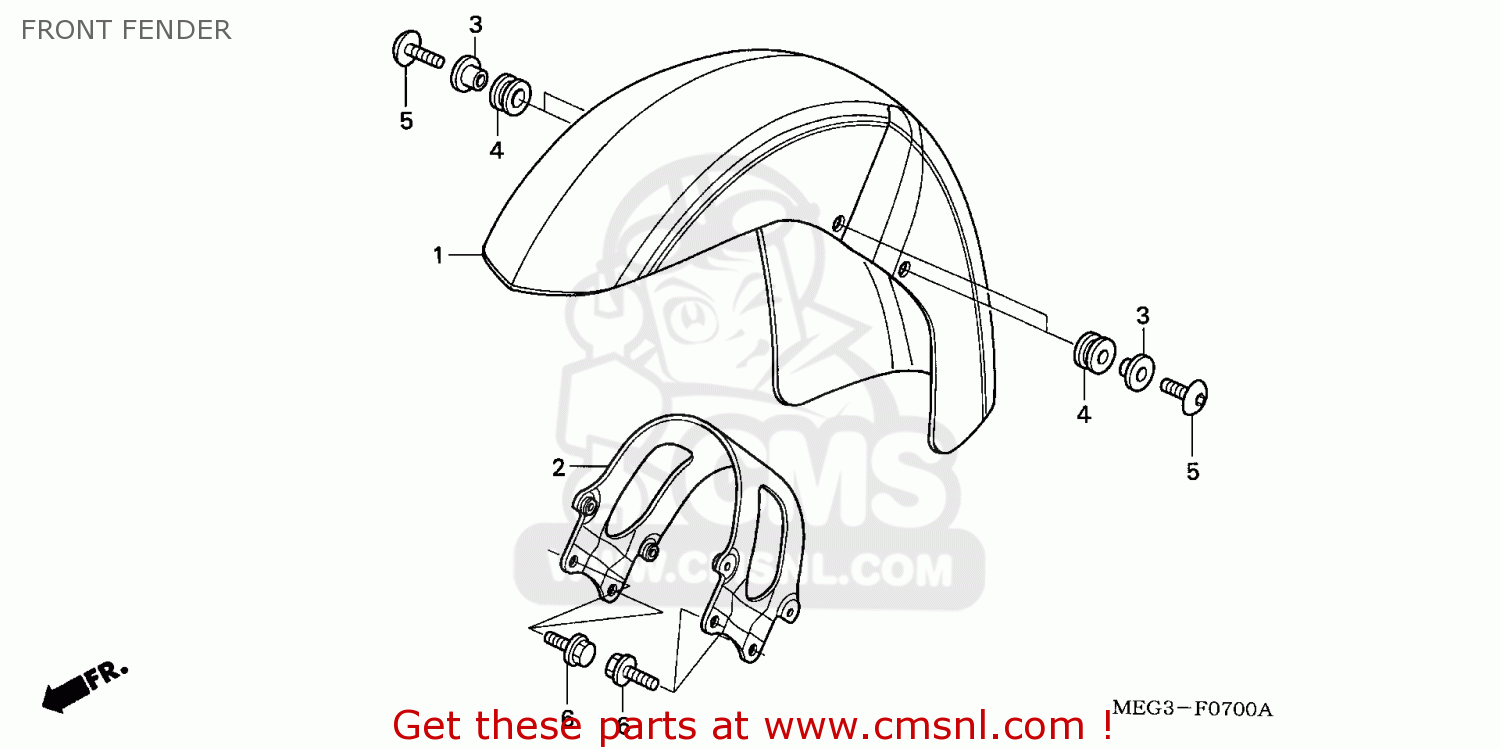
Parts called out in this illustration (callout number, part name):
1	SET ILLUST*TYPE1*
2	BRACE, FR FENDER
3	COLLAR,FR *TYPE2*
4	CUSHION,FR FENDER
5	BOLT SPECIAL 6X18
6	BOLT FLANGE 8X20
